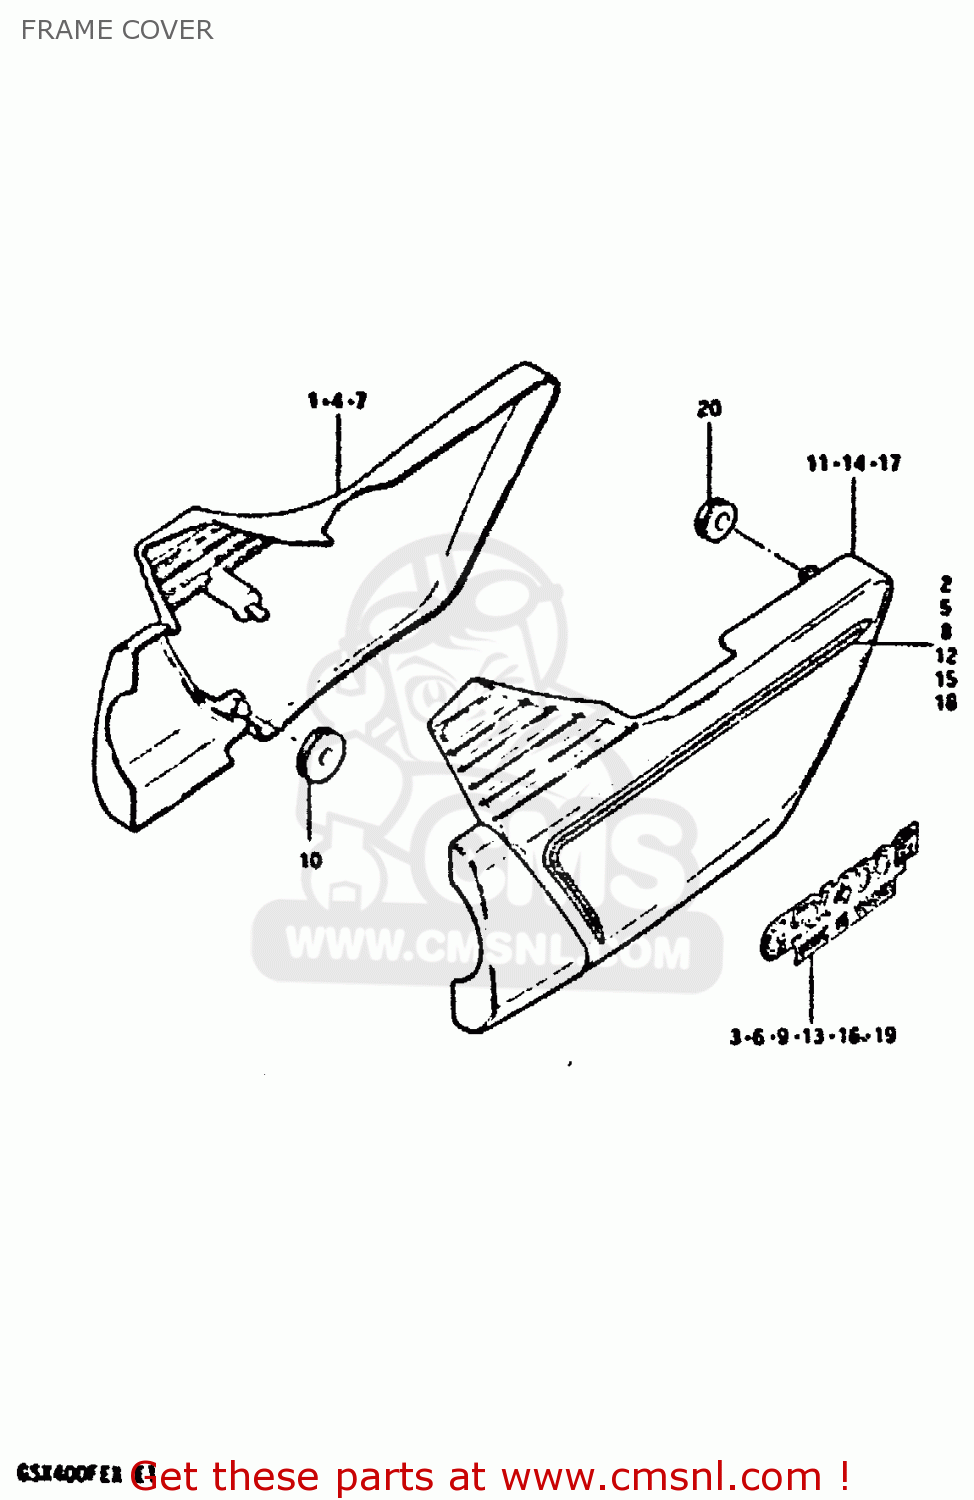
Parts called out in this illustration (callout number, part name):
1	COVER, FRAME RH (BLUE)
2	TAPE, RH
3	EMBLEM, LH
4	COVER,FRAME RH
5	TAPE, RH
6	EMBLEM, LH
7	COVER, FRAME RH (RED)
8	TAPE, RH
9	EMBLEM, RH
10	CUSHION
11	COVER, FRAME LH (BLUE)
12	TAPE, LH
13	EMBLEM, LH
14	COVER, FRAME LH
15	TAPE, LH
16	EMBLEM, LH
17	COVER,FRAME LH
18	TAPE, LH
19	EMBLEM, LH
20	CUSHION
